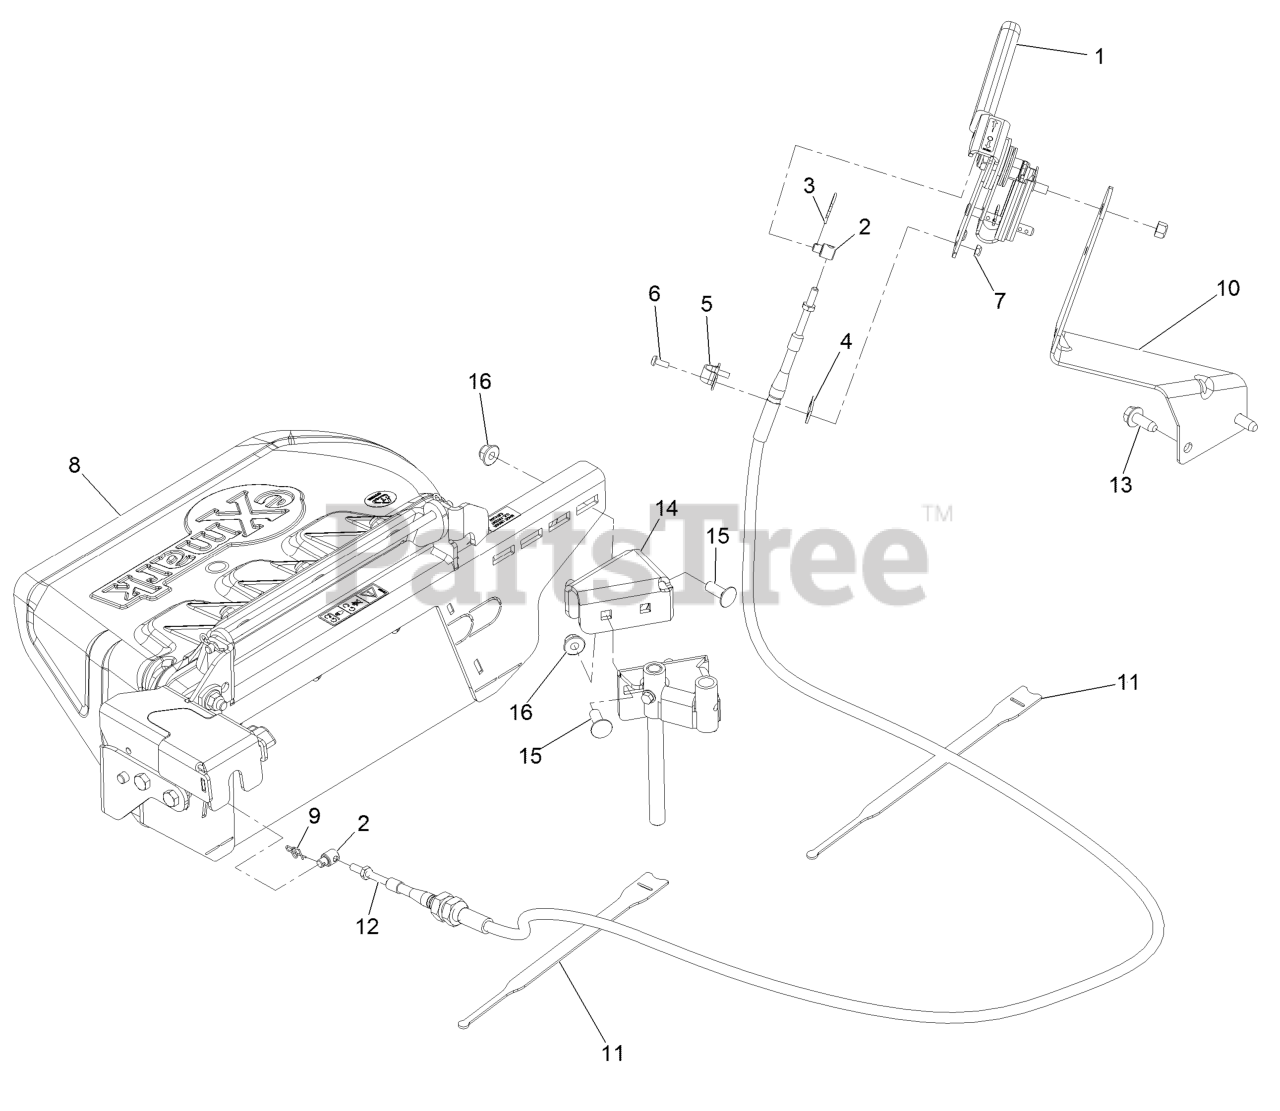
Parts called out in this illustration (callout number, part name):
1	ASM, Hand Lever
2	Pivot, Control Cable
3	Hairpin-Cotter
4	Shim,Control Cable
6	Screw-PPH #10-24 X 1/2
7	Nut-Nyloc #10-24 Thin
8	ASM, Ocd
9	Pin-Cotter, Locking
10	Bracket-Support Ocdc
11	Strap-Velcro, Cable Tie
12	Cable-Discharge Gate
13	Screw-Forming, Thread
14	Bracket-Ocd [red]
15	Bolt-Carriage 3/8-16 X 1
16	Nut-Nyloc 3/8-16 Flg
